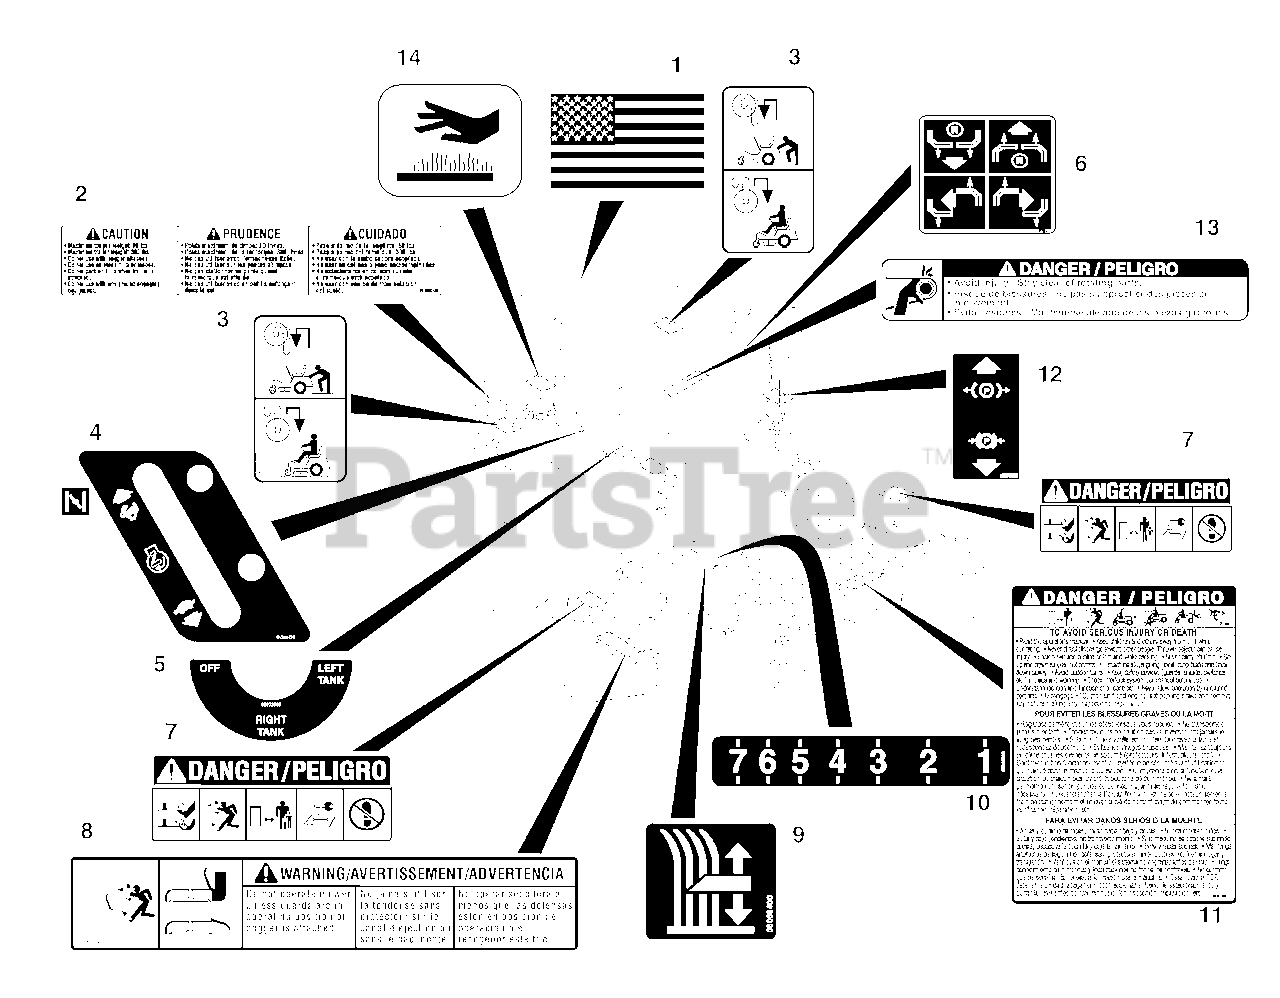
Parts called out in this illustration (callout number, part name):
1	Decal, American Flag
2	Decal, Trailer Hitch
3	Decal, Transmission Disconnect
4	Decal, Control
5	Decal, Fuel Value
6	Decal, Instructional Steering
7	Decal, Mower Pan Head Danger
8	Decal, Warning
9	Decal, Cut Height
10	Decal, Cut Height Zoom
11	Decal, Bilingual Danger
12	Decal, Parking Brake Lever
13	Decal, Danger
14	Decal, Hot Surface
